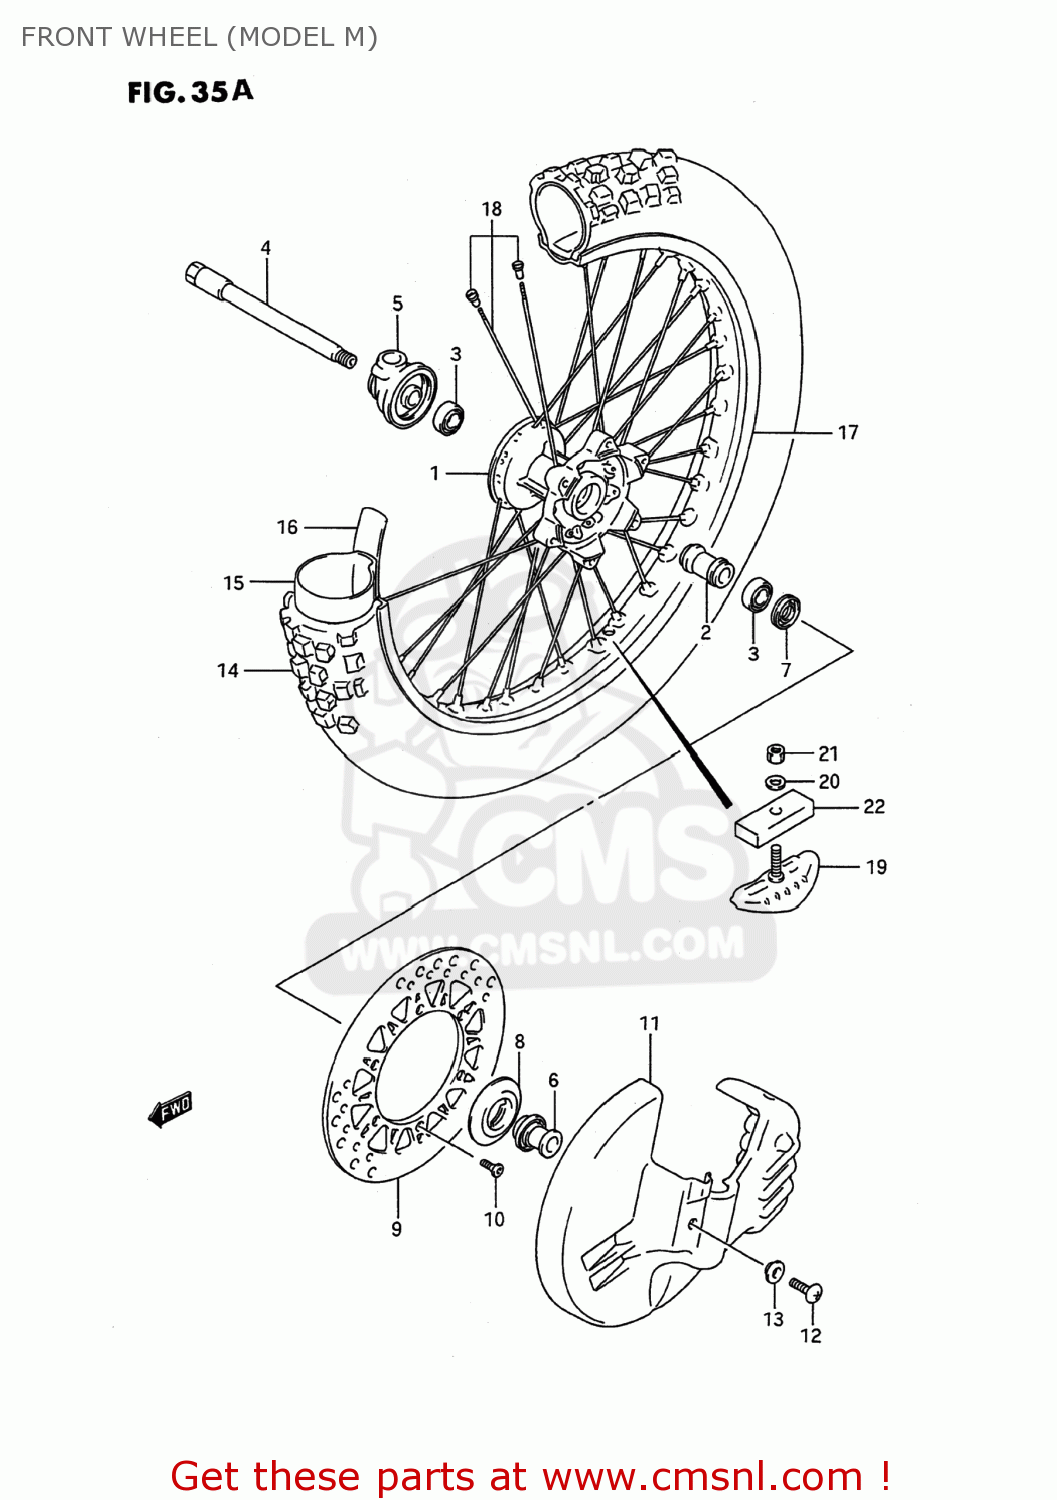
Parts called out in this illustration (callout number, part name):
1	HUB,FRONT WHEEL
2	SPACER,FR HUB BEARING
3	BEARING
4	AXLE,FRONT
5	BOX ASSY,SPEEDOMETER GEAR
6	SPACER,FR AXLE,L
7	SEAL,OIL(23X35X6)
8	CAP,FR HUB,L
9	DISC,BRAKE
10	SCREW
11	COVER,FRONT BRAKE DISC
12	SCREW 6X12
13	WASHER
14	TIRE,FRONT
15	TUBE
16	PROTECTOR,WHEEL,INNER
17	RIM,FRONT WHEEL (1.60X2
18	SPOKE SET,FRONT
19	STOPPER,BEAD
20	WASHER
21	NUT
22	CUSHION,BEAD STOPPER
